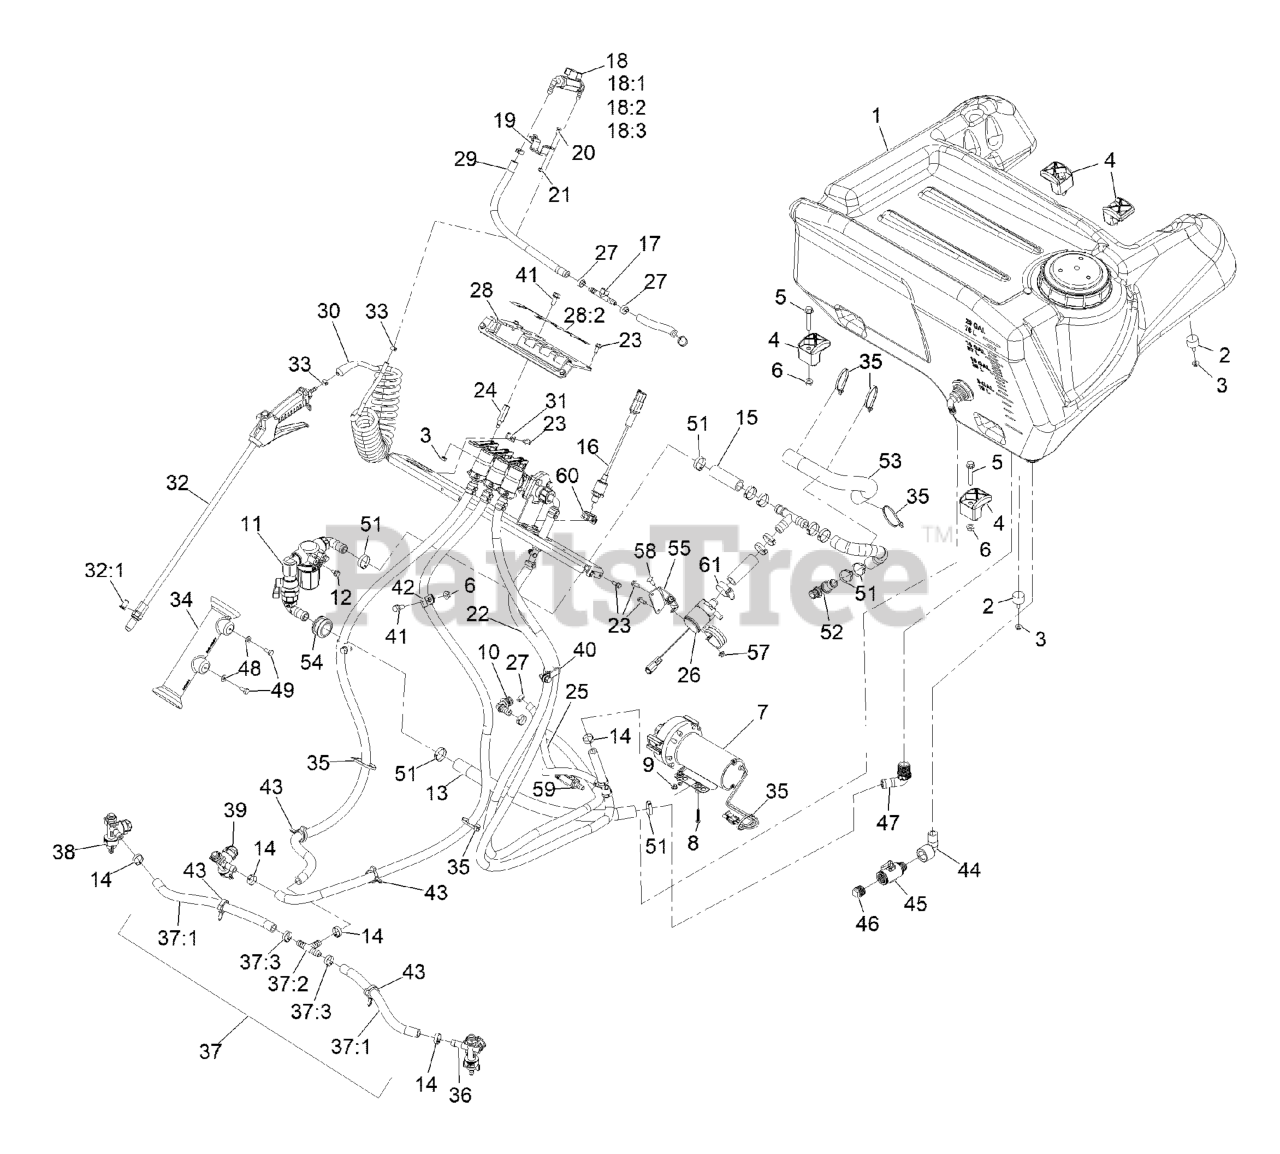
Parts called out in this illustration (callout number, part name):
1	Tank-Sprayer
5	SCREW-HHF
7	Pump-Diaphragm, 3.8 GPM
8	SCREW-SHWH
10	FITTING-ELBOW, BARBED
11	STRAINER ASM
12	SCREW-HHF
13	HOSE-WATER
14	CLAMP OETIKER 0.716"" CLOSED 0.826"" OPEN
15	ASM-, 3/4 Pvc Reinforced Water Hose
16	TRANSDUCER-PRESSURE
17	FITTING-TEE
18	Wand Control ASM
18:1	VALVE-BALL
18:2	FITTING-ELBOW-90
18:3	FITTING-ELBOW-90
19	BRACKET-VALVE
20	BOLT-CARR
21	NUT-LOCK, NI
22	Manifold-Valve, Control ASM
23	SCREW-HWH
24	Spacer, Manifold Mount
25	Hose-Water
26	Pump-Centrifugal
28	COVER-CONTROLS
28:2	Decal-Lever Control
29	HOSE-WATER, 3/8 PVC RED
30	Hose-Coiled, 04X15Ft
31	CLAMP-R
32	SPRAY WAND ASM
32:1	STRAINER-NOZZLE, 50M 5PSI
34	HOLDER-WAND
35	TIE-CABLE
36	LEFT NOZZLE SUB ASM
37	HOSE ASM
37:1	HOSE-WATER
37:2	FITTING-TEE
37:3	CLAMP OETIKER 0.716"" CLOSED 0.826"" OPEN
38	RIGHT NOZZLE SUB ASM
39	CENTER NOZZLE SUB ASM
41	SCREW-HHF
42	CLIP-LOOM
43	CLAMP-HOSE
44	ELBOW-90 DEG
45	MICROVALVE
47	ELBOW-HOSEBARB
48	WASHER-FLAT
49	SCREW-HH
52	FITTING-ELBOW
53	SLEEVE-CORRUGATED, SPLIT
54	GROMMET
55	Brkt-Recir Pump
58	SCREW-CARR
59	Valve-3/8 Check
60	R-Clamp
61	CLAMP-HOSE
